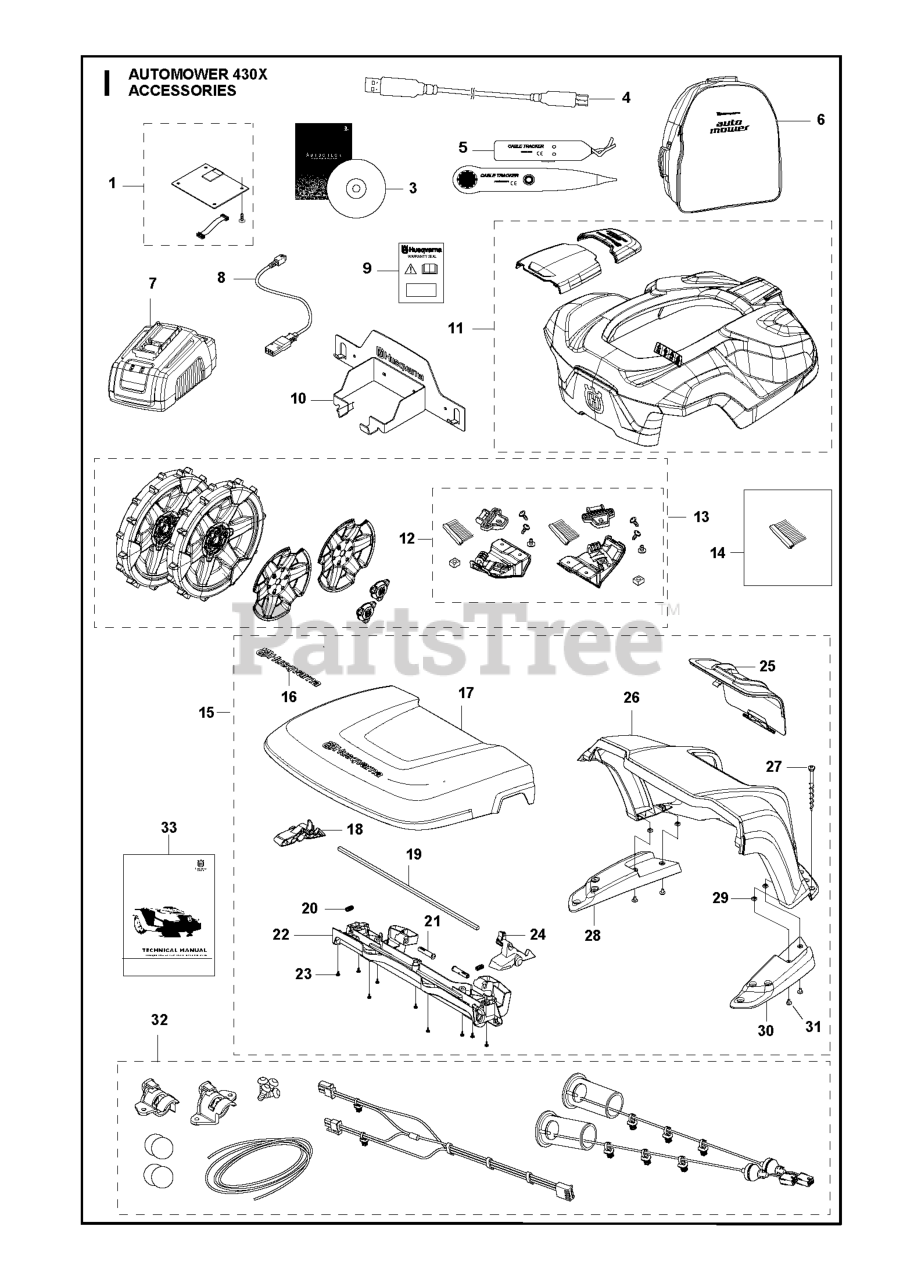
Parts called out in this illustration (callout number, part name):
1	CONNECT MODULE 315 / 430X
3	DVD AUTOCHECK EXP SERVICE
4	CABLE WHITE ALT GREY
5	TEST EQUIPMENT
6	BAG
7	CHARGER BATTERY TEST
8	CABLE ASSY QUICK CHARGER
9	LABEL WARRANTY SEAL DEALER
10	MISC. BLISTER WALL HANGER
11	WHITE BODY KIT 430
12	BRUSH KIT 430/450
13	REAR WHEEL KIT W/ BRUSHES
14	WHEEL BRUSH REFILL KIT
15	430/450 HOUSE KIT
16	DECAL.HUSQVARNA.210MM
17	KIT LID - AUTOMOWER HOUSE
18	HANDLE RELEASE LEFT
19	ROD
20	SPRING SPRING CAP
21	HINGE PIN
22	BEAM
23	SCREW 14MM
24	HANDLE RELEASE RIGHT
25	HATCH
26	COVER BASE P2 HOUSE
27	SCREW KIT CS
28	SUPPORT BASE LEFT
29	NUT
30	SUPPORT BASE RIGHT
31	SCREW IHPANM M6X25 4.6 ZP-BC
32	430 HEADLIGHT KIT
